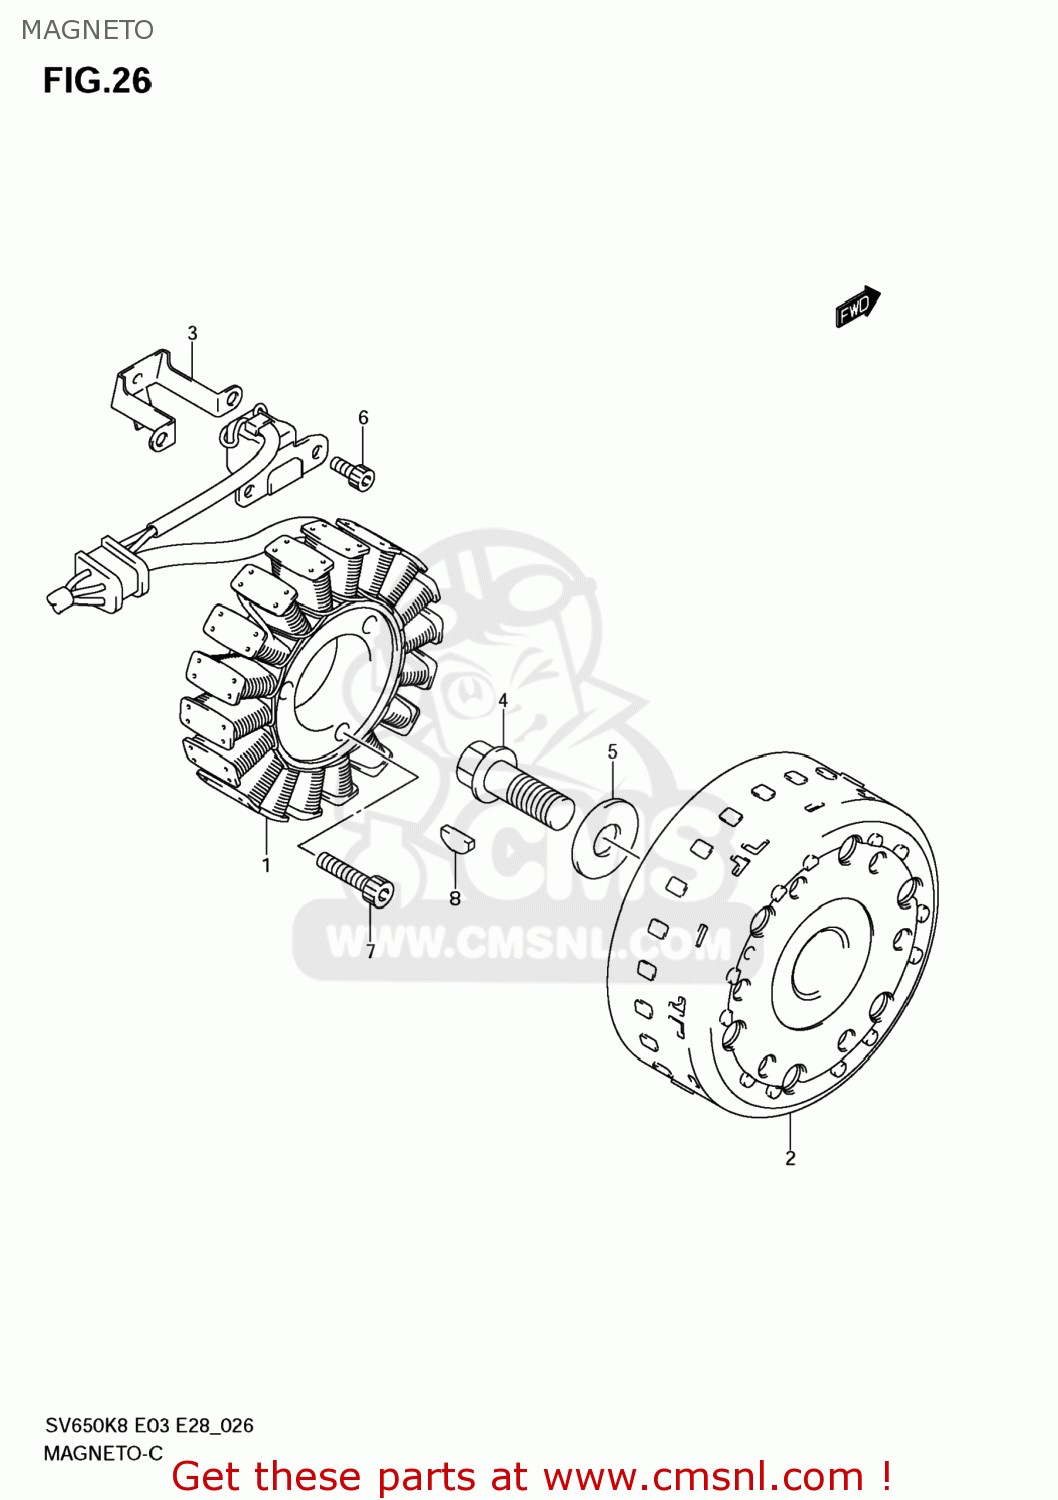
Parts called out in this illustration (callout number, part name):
1	STATOR ASSY
2	ROTOR ASSY
3	CLAMP,MAGNETO LEAD
4	BOLT(12X40)
5	WASHER(12X30X3)
6	BOLT
7	BOLT
8	KEY
